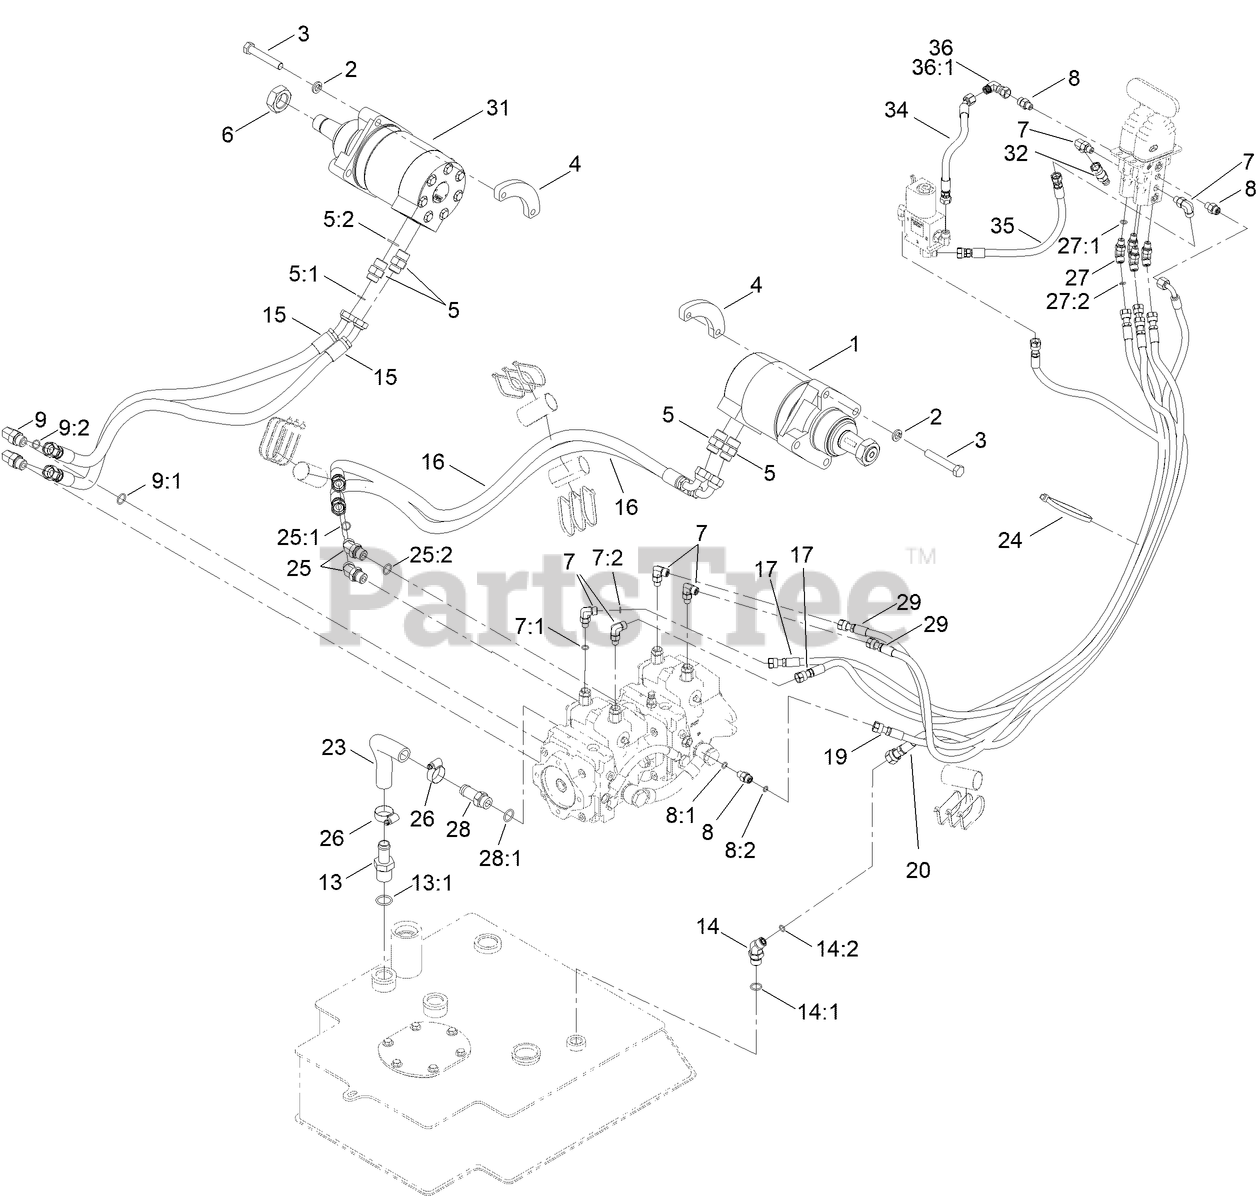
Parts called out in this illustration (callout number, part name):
1	MOTOR-HYD
2	WASHER-LOCK
3	SCREW-HH, TAP
4	PLATE-MOUNTING, WHEELMOTOR
5	FITTING-STRAIGHT
5:1	O-RING
5:2	O-RING
6	NUT-HEX
7	FITTING-ELBOW, 90 DEG
7:1	O-RING
7:2	O-RING
8	FITTING-STRAIGHT
8:1	O-RING
8:2	O-RING
9	FITTING-ELBOW, 90 DEG
9:1	O-RING
9:2	O-RING
13	FITTING
13:1	O-RING
14	FITTING-HYD, 45 DEG
14:1	O-RING
14:2	O-RING
15	HOSE-HYD
16	HOSE-HYD
17	HYD HOSE ASM
19	HYD HOSE ASM
20	HYD HOSE ASM
23	HOSE-RETURN
24	TIE-CABLE
25	FITTING-HYD, 45 DEG
25:1	O-RING
25:2	O-RING
26	CLAMP-HOSE
27	FITTING-HYD, 45 DEG
27:1	O-RING
27:2	O-RING
28	FITTING-STR
28:1	O-RING
29	HYD HOSE ASM
31	MOTOR-HYD
32	NIPPLE-TEST
34	HOSE ASM
35	HOSE ASM
36	FITTING-ADAPTOR
36:1	O-RING
